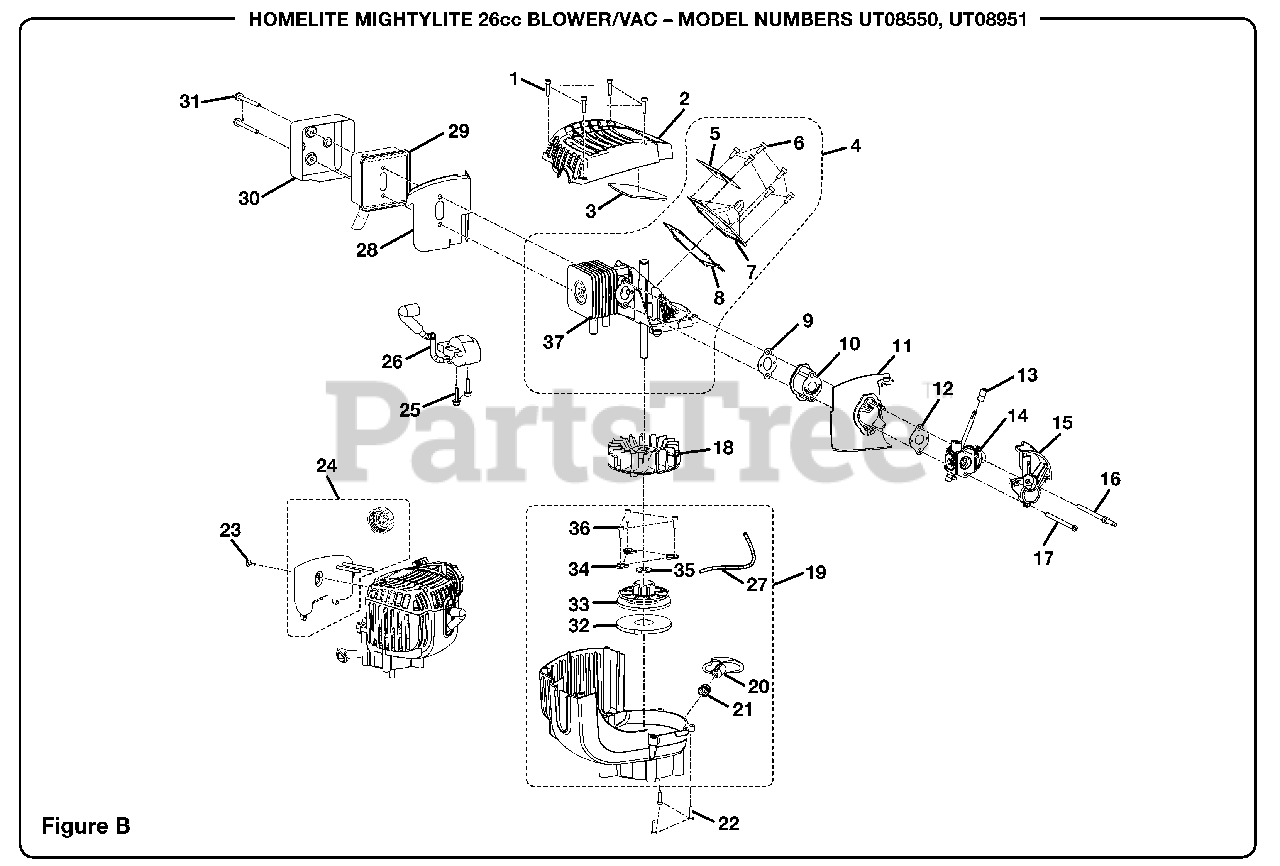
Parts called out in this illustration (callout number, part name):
1	Screw (M4 x 18 mm)
2	Upper Housing
3	Heat Shield Gasket
4	Short Block Assembly
5	Cylinder Heat Shield
6	Screw (M4 x 12 mm)
7	Crankcase Cover
8	Crankcase Cover Gasket
9	Intake Gasket
11	Baffle Plate
12	Carburetor Gasket
13	Throttle Lever
14	Carburetor
15	Air Box Base
16	Hex Bolt (Double Sided)
17	Screw (M5 x 70 mm)
18	Flywheel Assembly
19	Lower Housing with Starter Assembly
20	Starter Grip
22	Screw (M4 x 16 mm)
23	Screw (M4, special)
24	Fuel Tank with Cap Assembly
25	Screw (M4 x 19 mm)
26	Ignition Module
27	Starter Rope
28	Muffler Gasket
29	Muffler Assembly
30	Heat Shield
31	Screw (10-24 x 2-3/16 in.)
32	Spring & Container Assembly
33	Starter Pulley
34	Pulley Retainer
35	Flat Washer
36	Screw (M4 x 14 mm)
37	Cylinder
